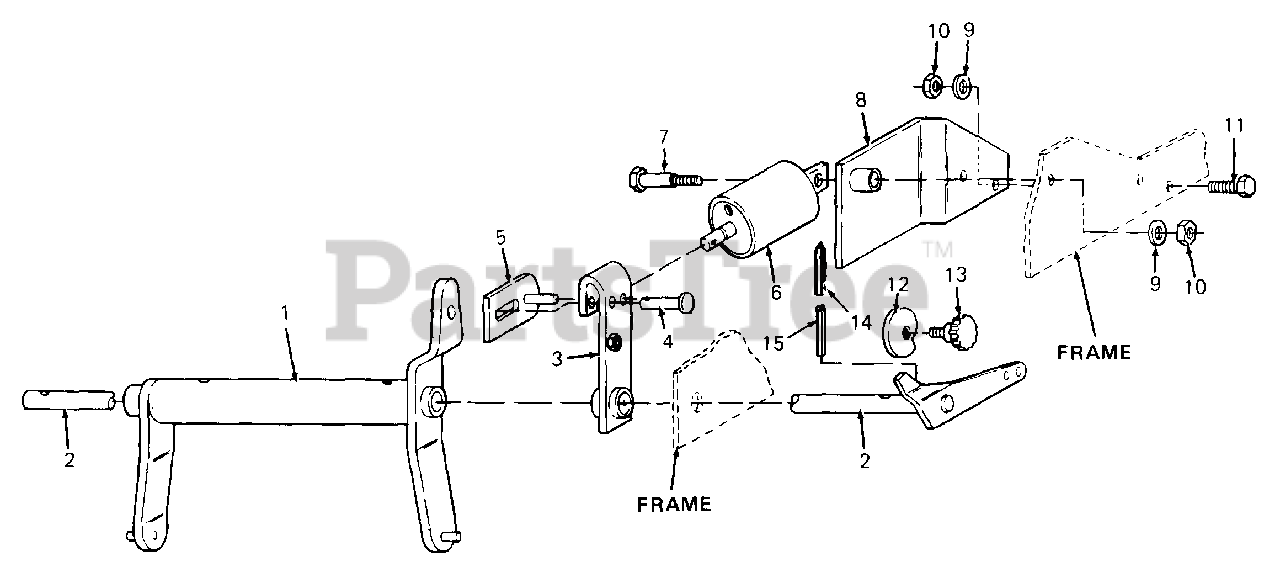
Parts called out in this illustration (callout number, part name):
1	Lift Assy, Rockshaft
2	Rockshaft Assy
3	Bracket, Lift
4	Pin, Clevis, 1/2 Dia x 2.172 Lg
5	Pin Assy, Lift
6	Cylinder, Hydraulic
7	Bolt, Shoulder
8	Bracket, Cylinder
9	Washer, Flat, .531 x 1.06 x .134 Thk
10	Nut, Hex Center Lock, 1/2-13 GR5
11	Screw, Hex Cap, 1/2-13 x 1.25 Lg GR5
14	Pointer, Lift
15	Pin, Roll, 3/16 Dia x 3.0 Lg
